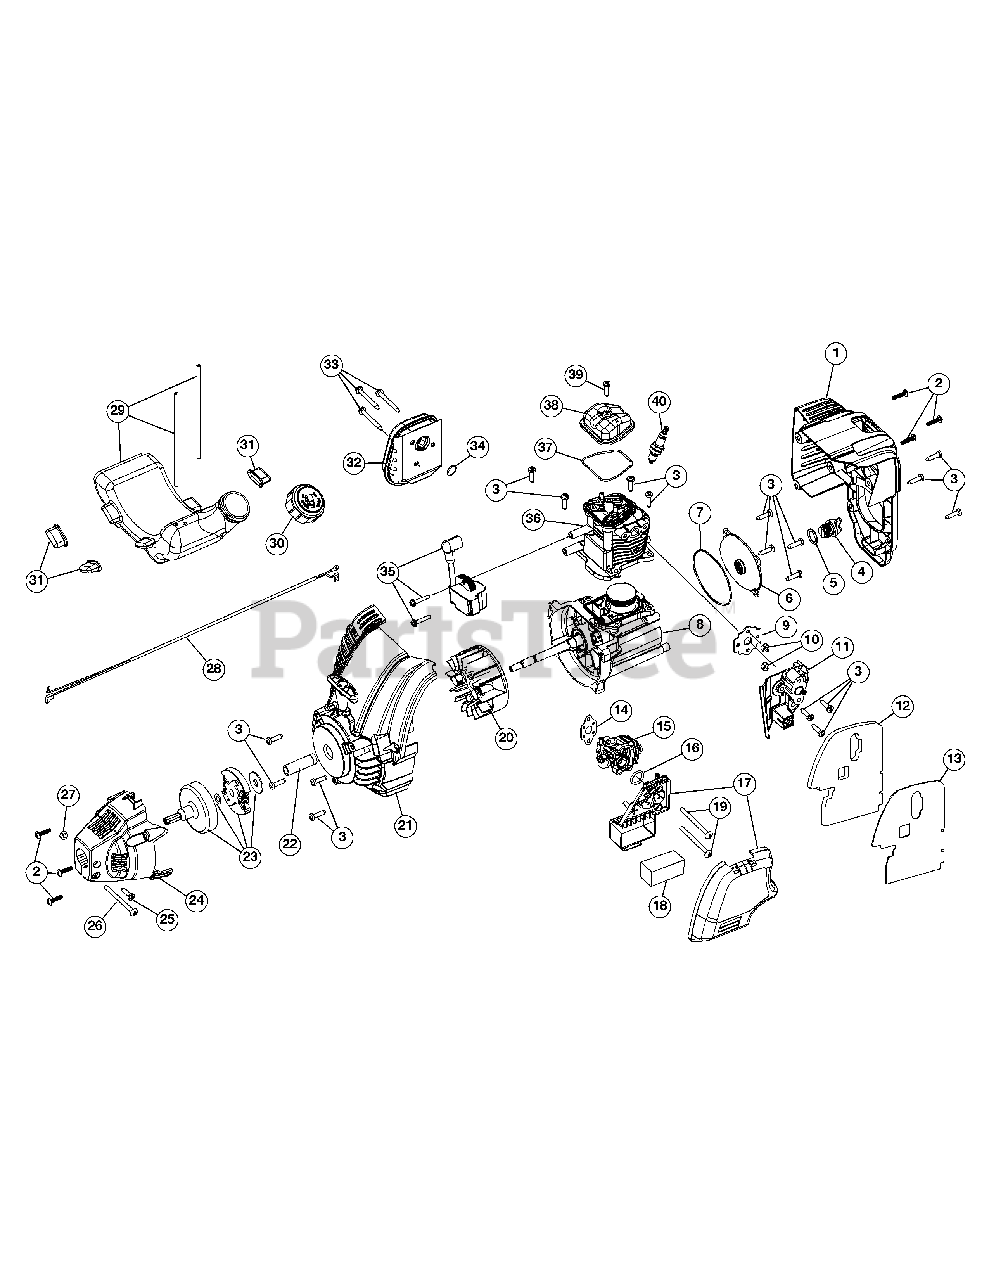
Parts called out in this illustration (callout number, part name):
1	Engine Cover Assembly (Incl. 2 & 3)
2	Cover Screw
4	Oil Plug (Incl. 5)
5	Oil Plug O-Ring
6	Crankcase Cover
7	Crankcase Cover O-Ring
8	Crankcase Assembly (Incl. 7)
9	Insulator Gasket
11	Insulator
12	Heat Shield
13	Gasket
15	Carburetor
17	Air Cleaner Cover Assembly (Incl. 18)
18	Air Filter
20	Flywheel Assembly
21	Starter Housing Assembly (Incl. 3)
22	Powershaft Spacer
23	Clutch Assembly
24	Clutch Cover (Incl. 2)
25	Anti-Rotation Screw
26	Clamp Screw
28	Lead Wires
29	Fuel Tank Assembly with Fuel Lines (Incl. 30)
30	Fuel Tank Cap
31	Fuel Tank Pads
32	Muffler Assembly (Incl. 33 & 34)
33	Muffler Screw
34	Muffler Gasket
35	Module Assembly
36	Cylinder Assembly (Incl. 38 & 39)
37	Rocker Cover O-Ring
38	Rocker Cover
39	Rocker Cover Screw
40	Spark Plug
